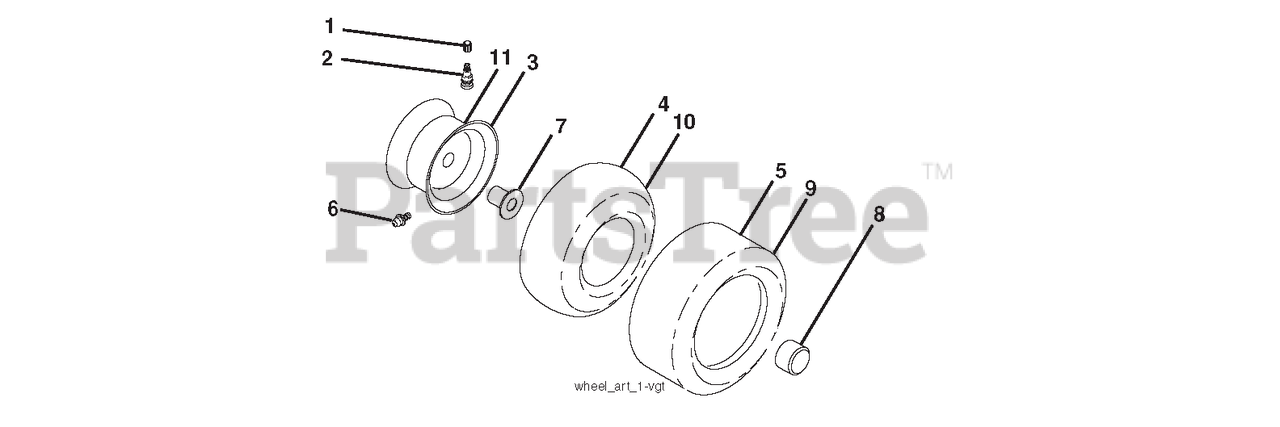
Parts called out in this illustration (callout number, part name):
1	CAP.VALVE.TIRE
2	STEM.VALVE
3	RIM ASSEMBLY 6" FRONT
4	TUBE.INNER.FRONT.#35060
5	TIRE.F.TS.15 X 6.0 - 6.SERVICE
6	FITTING, GREASE
7	BEARING FLANGE
8	CAP AXLE (FRONT WHEEL ONLY)
9	TIRE.R.TS.20 X 8-8.C.SERVICE
10	TUBE, REAR
11	RIM ASSEMBLY 8" REAR
